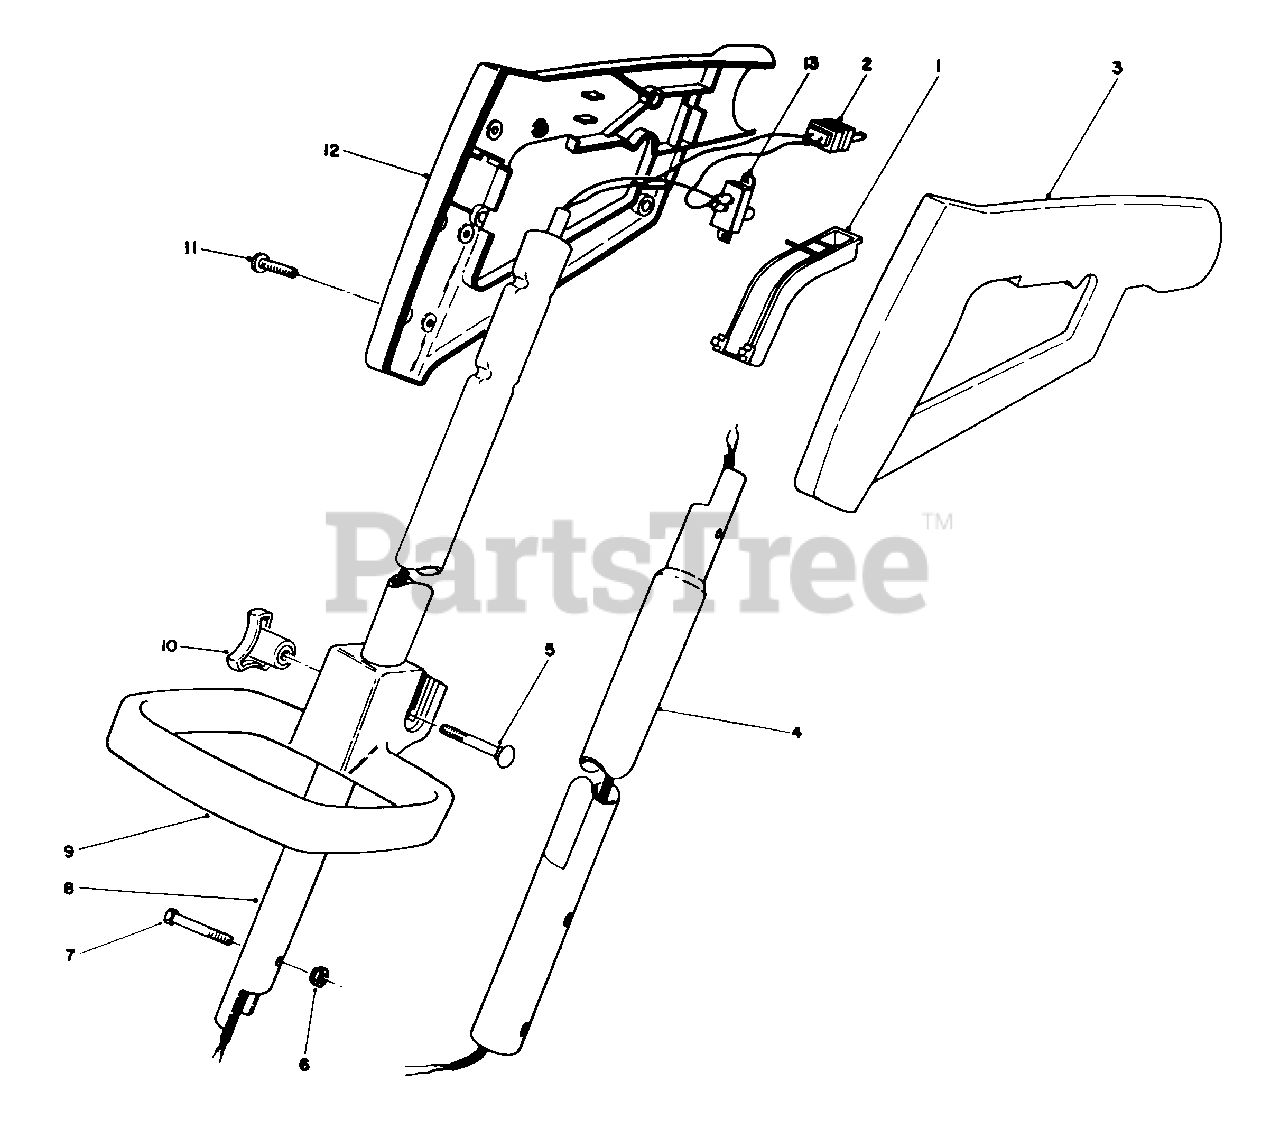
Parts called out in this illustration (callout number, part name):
1	Bar-Switch
2	Harness-Wiring
3	Grip-Left Handle
4	Tube-Lower
5	Bolt-Carriage
6	Nut-Lock
7	Screw-Machine
8	Tube-Upper
9	Handle-Adjustable
11	Screw
12	Grip-Right Handle
13	Switch-Single Speed
